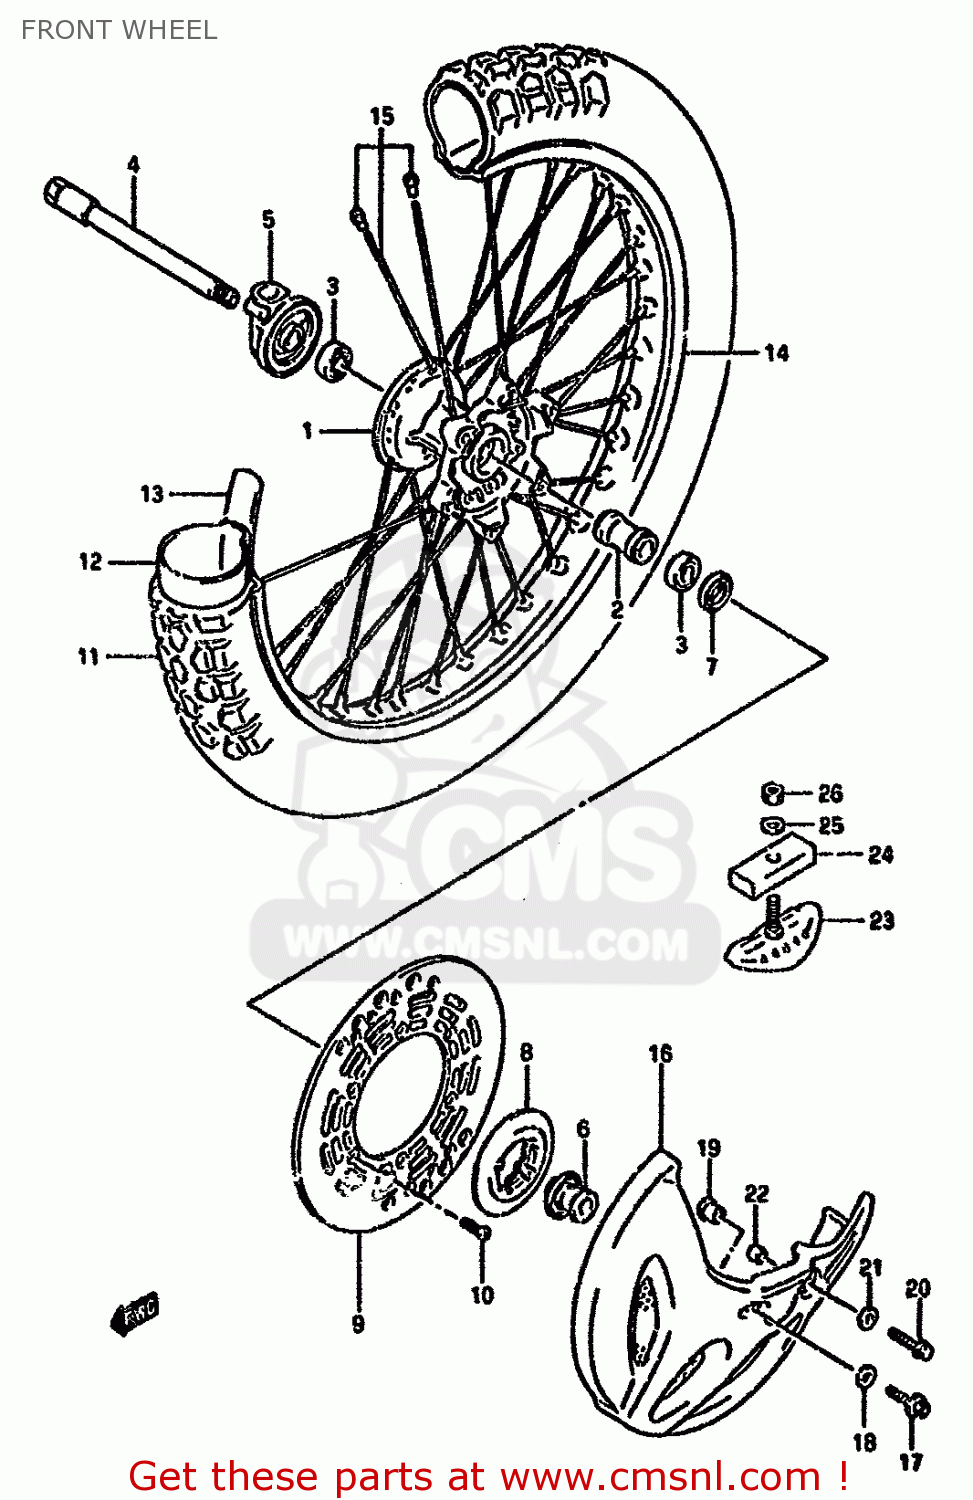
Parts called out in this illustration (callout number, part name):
1	HUB,FRONT WHEEL
2	SPACER,FR HUB BEARING
3	BEARING
4	AXLE,FR
5	BOX ASSY,SPEEDOMETER GEAR
6	SPACER,FR AXLE,L
7	SEAL,OIL(23X35X6)
8	CAP,FR HUB,L
9	DISC,FR BRAKE
10	SCREW,BRAKE DISC
11	TIRE,FRONT 80/100-21
12	TUBE
13	PROTECTOR,WHEEL,INNER
14	RIM,FRONT WHEEL (1.60X2
15	SPOKE SET,FRONT
16	COVER,FR BRAKE DISC
17	BOLT
18	WASHER(8.5X18X1)
19	WASHER (8.5X16X1.6)
20	BOLT
21	WASHER(6.5X18X1)
22	SPACER(6.1X8X14.5)
23	STOPPER,BEAD
24	CUSHION,BEAD STOPPER
25	WASHER
26	NUT
